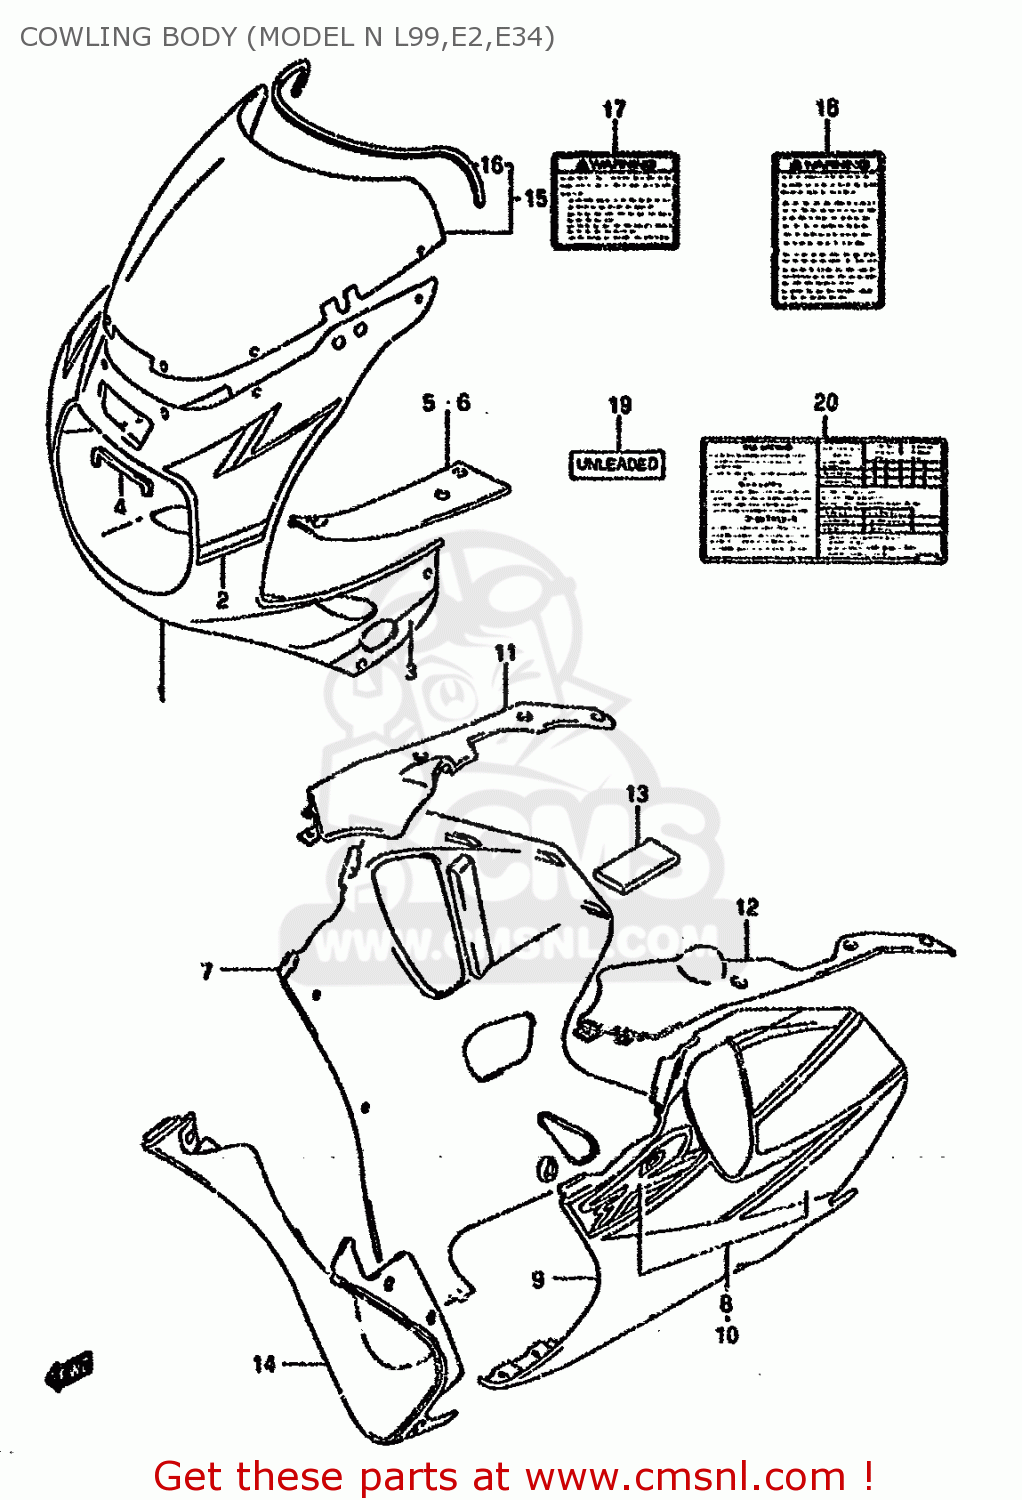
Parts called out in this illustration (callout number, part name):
1	COWLING ASSY,BODY (WHITE)
2	TAPE SET,UPPER
3	TAPE SET,UPPER SIDE
4	CUSHION,FR POSITION LAMP
5	PANEL,UPR,R
6	PANEL,UPR,L
7	COWLING ASSY,UNDER RH (WHITE)
8	TAPE SET,UNDER RH
9	COWLING ASSY,UNDER LH (WHITE)
10	TAPE SET,COWL UNDER,L
11	PANEL,LWR,R
12	PANEL,LWR,L
13	CUSHION,PANEL
14	COWLING,UNDER,CENTER
15	WINDSCREEN SET
16	MOLDING
17	LABEL
18	LABEL (WARNING SCREEN)
19	LABEL,CAUTION
20	LABEL,TIRE AIR PRESSURE
